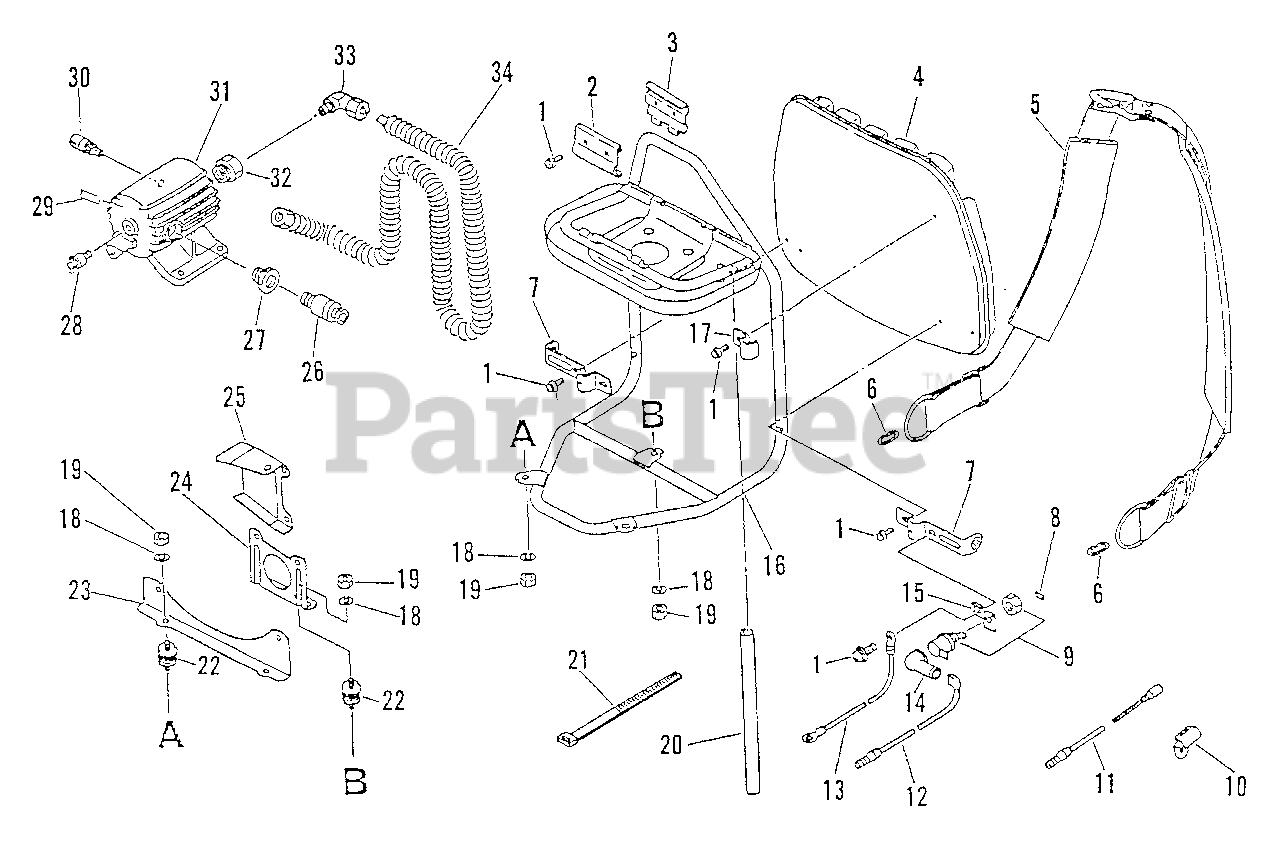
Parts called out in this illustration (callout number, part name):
1	SCREW 5×14
2	BACKPACK STRAP ASSY
3	HARNESS ASSY
4	CUSHION, BACKPACK
5	STRAP, BACKPACK
6	RING, HARNESS
7	BRACKET - LOWER
8	LABEL, ON-OFF
9	SWITCH, ON-OFF
10	CLIP
11	LEAD (A)
13	LEAD - GROUND
14	SLEEVE
15	BRACKET, SWITCH
16	FRAME, BACKPACK
17	BRACKET, CUSHION
18	WASHER, SPRING 5
19	NUT - 5 -- FLANGE
20	PIPE, FUEL
21	TIE, CABLE
23	BRACKET, COMPRESSOR
24	BRACKET, COMPRESSOR
25	DUCT, AIR
26	VALVE, SAFETY
27	BOLT, EYE
28	VALVE
29	LABEL - CAUTION -- HOT
30	CONNECTOR
31	TANK, AIR
32	BOLT, EYE
33	ELBOW, HOSE - 1/4
34	HOSE, COOLING
